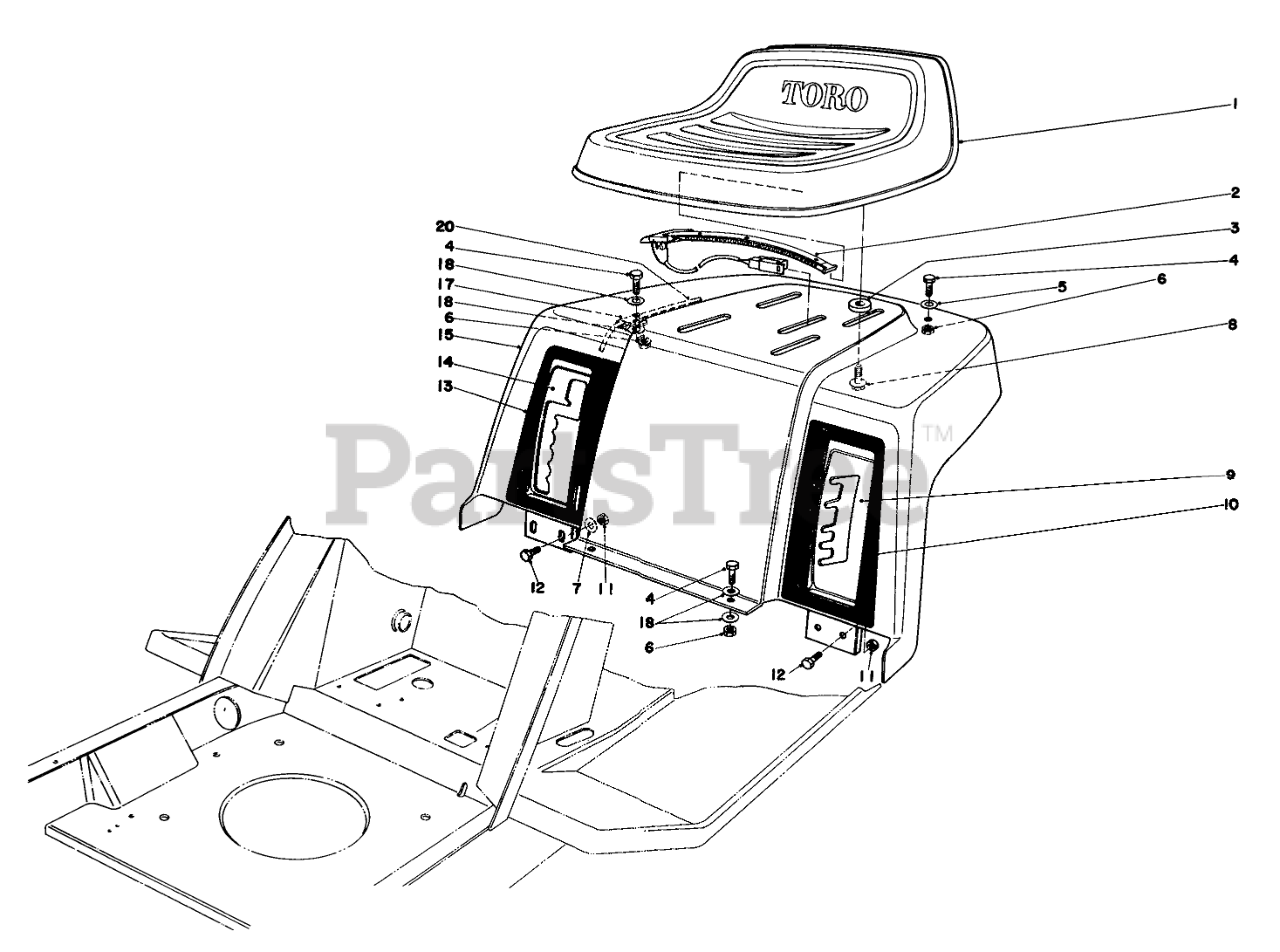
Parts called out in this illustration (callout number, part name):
1	Seat
2	SWITCH-SEAT
3	SPACER-PIN, MOUNTING
4	SCREW-HH
5	WASHER-FLAT
6	NUT-LOCK, CONE
7	WASHER-PLAIN
8	SCREW-HHF
9	Quadrant Height of Cut
10	Decal Height of Cut
11	NUT-LOCK, CONE
12	SCREW-HH
13	Decal-Transmission
14	DETENT PLATE B
15	Rear Body
17	CLIP-FUEL LINE
18	WASHER-FLAT
20	Wire Harness
